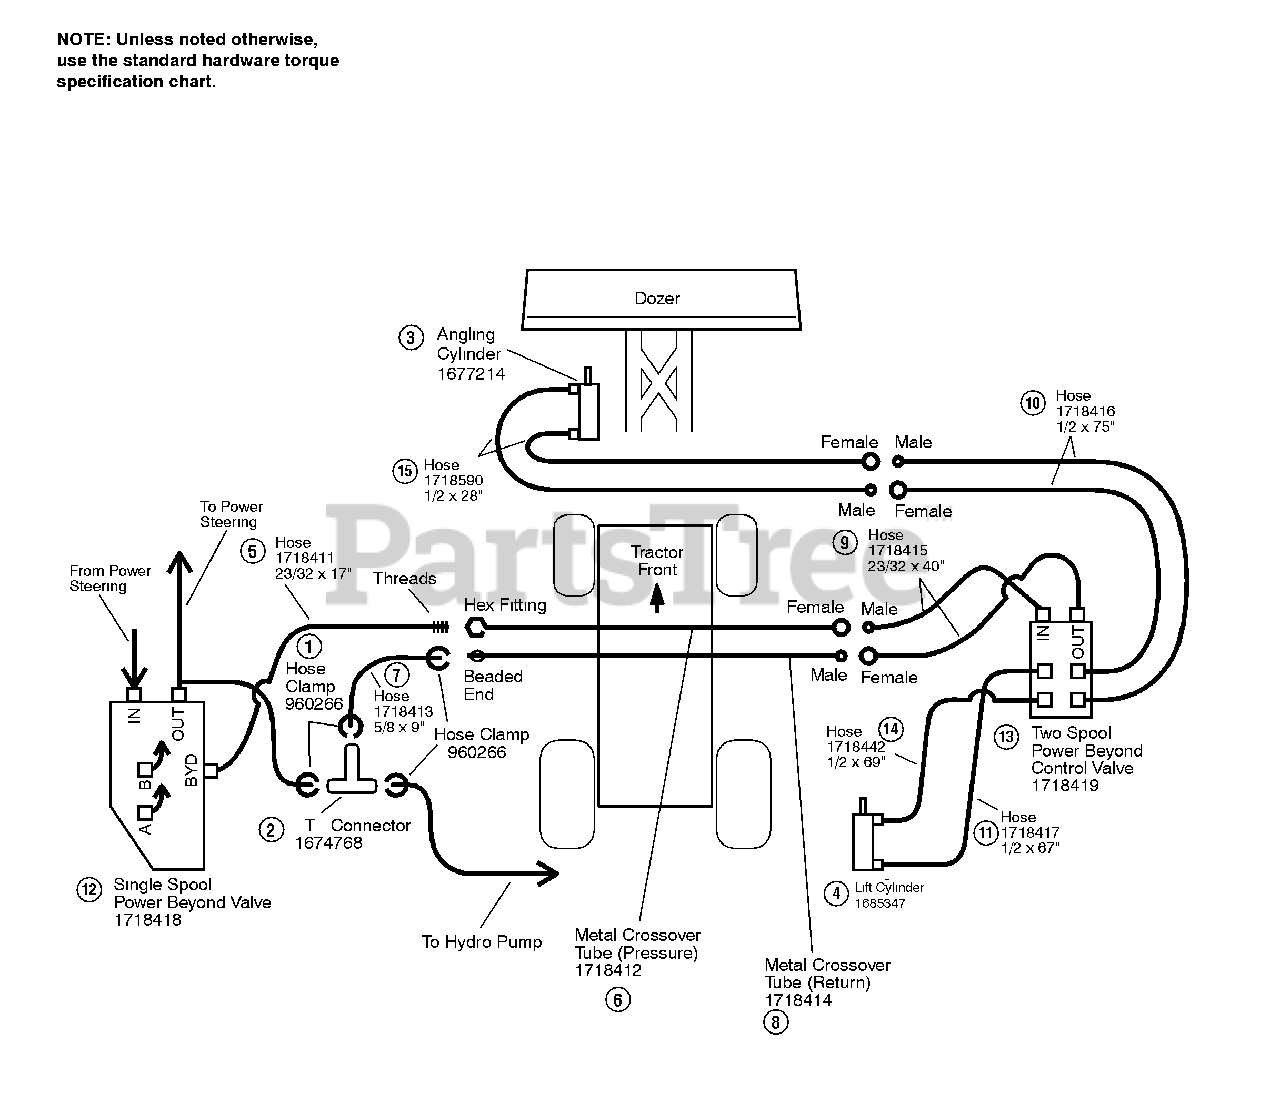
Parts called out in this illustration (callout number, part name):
1	CLAMP, Hose, Worm
2	FITTING, Hose, Tee
3	CYLINDER, Angling
4	CYLINDER, Lift
5	HOSE ASSEMBLY, 23/32" x 17"
6	PRESSURE TUBE ASSEMBLY
7	HOSE, Hydraulic 3/8" ID x 9"
8	RETURN TUBE ASSEMBLY
9	HOSE, Hydraulic, 23/32" x 40"
10	HOSE, Hydraulic, 1/2" x 75"
11	HOSE, Hydraulic, 1/2" x 67"
12	CONTROL VALVE, Single Spool, Power Beyond
13	CONTROL VALVE, Two Spool, Power Beyond
14	HOSE, Hydraulic, 1/2 x 69"
15	HOSE, Hydraulic, 1/2" x 28"
